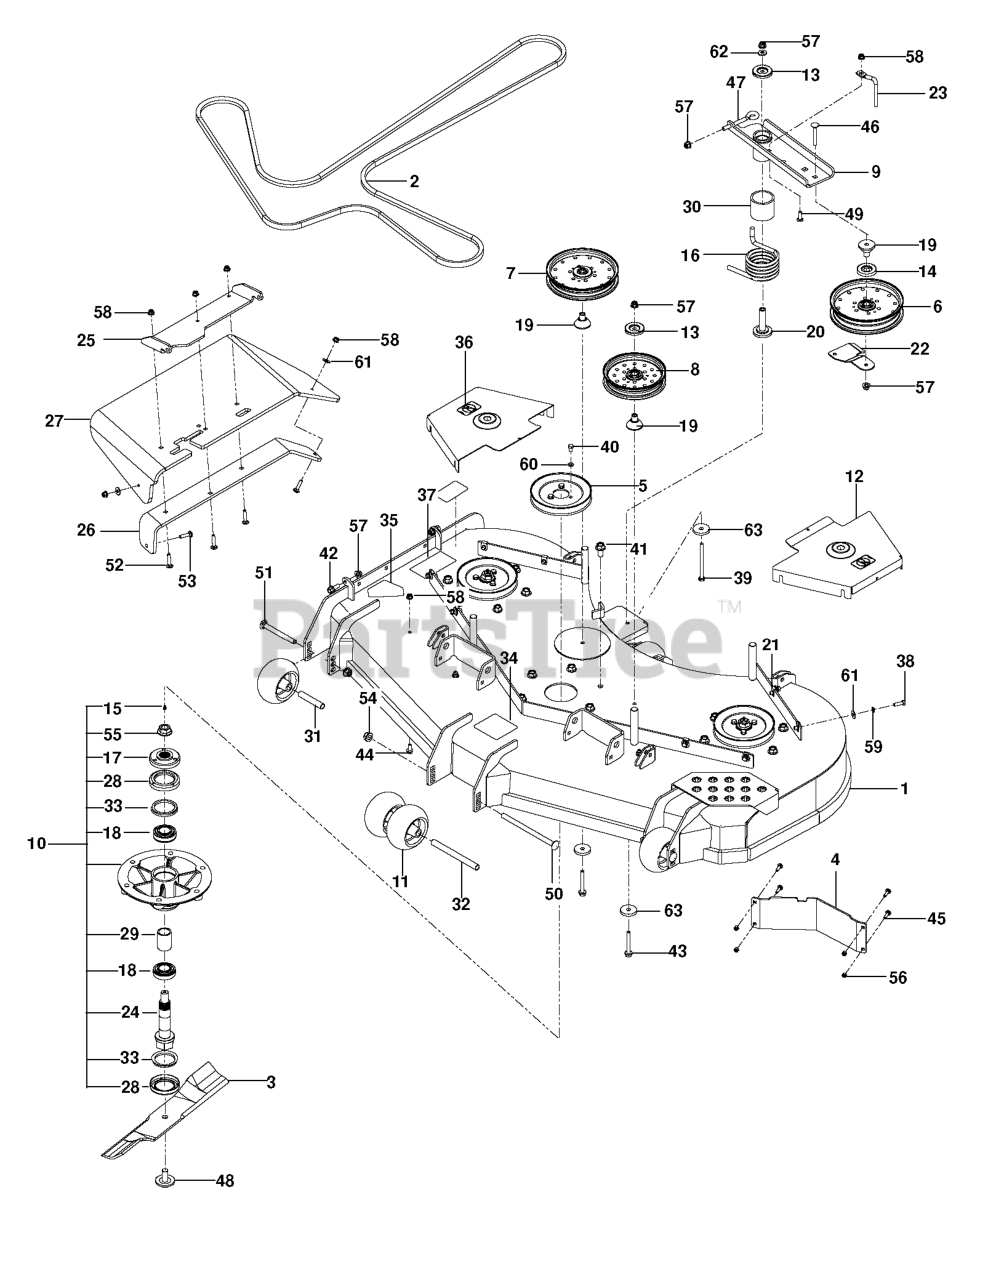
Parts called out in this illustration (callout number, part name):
1	DECK.SVC W/DECALS.60.ORANGE
2	BELT, DECK
3	BLADE - HEAVY DUTY 21"
4	BAFFLE, DIVERTER 54"/60" LH
5	PULLEY - 6.57
6	PULLEY - IDLER 7"
7	PULLEY - 7" NARROW
8	PULLEY IDLER, 6" NARROW
9	ASSY, IDLER ARM, PZ
10	SPINDLE ASM. 10"
11	ROLLER, GAUGE .635 BORN
12	SHIELD,BELT, 60" ORANGE
13	DUST SHIELD
14	SHIELD, DUST
15	ZERK
16	SPRING, TORSION, IDLER
17	HUB - PULLEY
18	BEARING - 206KRR8
19	BEARING, IDLER ARM
20	BEARING, IDLER PIVOT
21	U-CLIP 5/16-18 NUT RETAINER
22	BELT.GUIDE.BLACK
23	BELT KEEPER
24	SHAFT - SPINDLE
25	BRKT - CHUTE MTG BLACK
26	BRKT, CHUTE SUPPORT BLACK
27	CHUTE, DISCHARGE 48-52
28	CUP - DEBRIS
29	SPACER - BEARING
30	SPACER, IDLER PIVOT
31	TUBE, ROLLER AXLE
32	TUBE, ROLLER AXLE LONG
33	V-RING, 55MM
34	DECAL, BELT ROUTING
35	DECAL, CPSC
36	DECAL, NO STEP
37	DECAL, EURO SEVERING
38	HCS 5/16C X 1
39	HCS 3/8-16 X 4-1/2 GR 8 ZD
40	HCS 5/16-18 X 1/2 GR 5 ZD
41	HHFS 1/2-13 X 1 GR5 ZD
42	HHFS 3/8-16 X 1 GRD 5 ZD
43	HHFS 3/8-16 X 2 3/4
44	HHFS 5/16-18 X 3/4
45	1/4-20X3/4 CARR BLT
46	CARRIAGE BOLT 3/8-16 X
47	EYE BOLT, 3/8 X 4"
48	BLADE BOLT/WASHER
49	RHSSNB 5/16C X 1.0
50	RHSNB 1/2-13 X 8 GR5 ZD
51	RHSNB 1/2-13 X 4.75 GR5 ZD
52	RHSNB 5/16-18 X 1-1/2 GR 5 ZD
53	BOLT, CARRIAGE 5/16X1-1/4
54	NUT, 1/2-13 HEX FLG NYLOC ZD
55	NUT FLANGE 3/4-16
56	NUT.1/4-20.HEX.NYLOC.ZD
57	NUT 3/8-16 HEX FLG NYLOC ZD
58	5/16-18 NYLOC FLANGE NUT
59	WASHER.LOCK.HVY.HLCL.SPR.5/16
60	WASH 5/16 DISC SPRING ZD
61	WASHER 5/16 FLAT
62	WASHER, 3/8 THICK
63	SPINDLE WASHER
